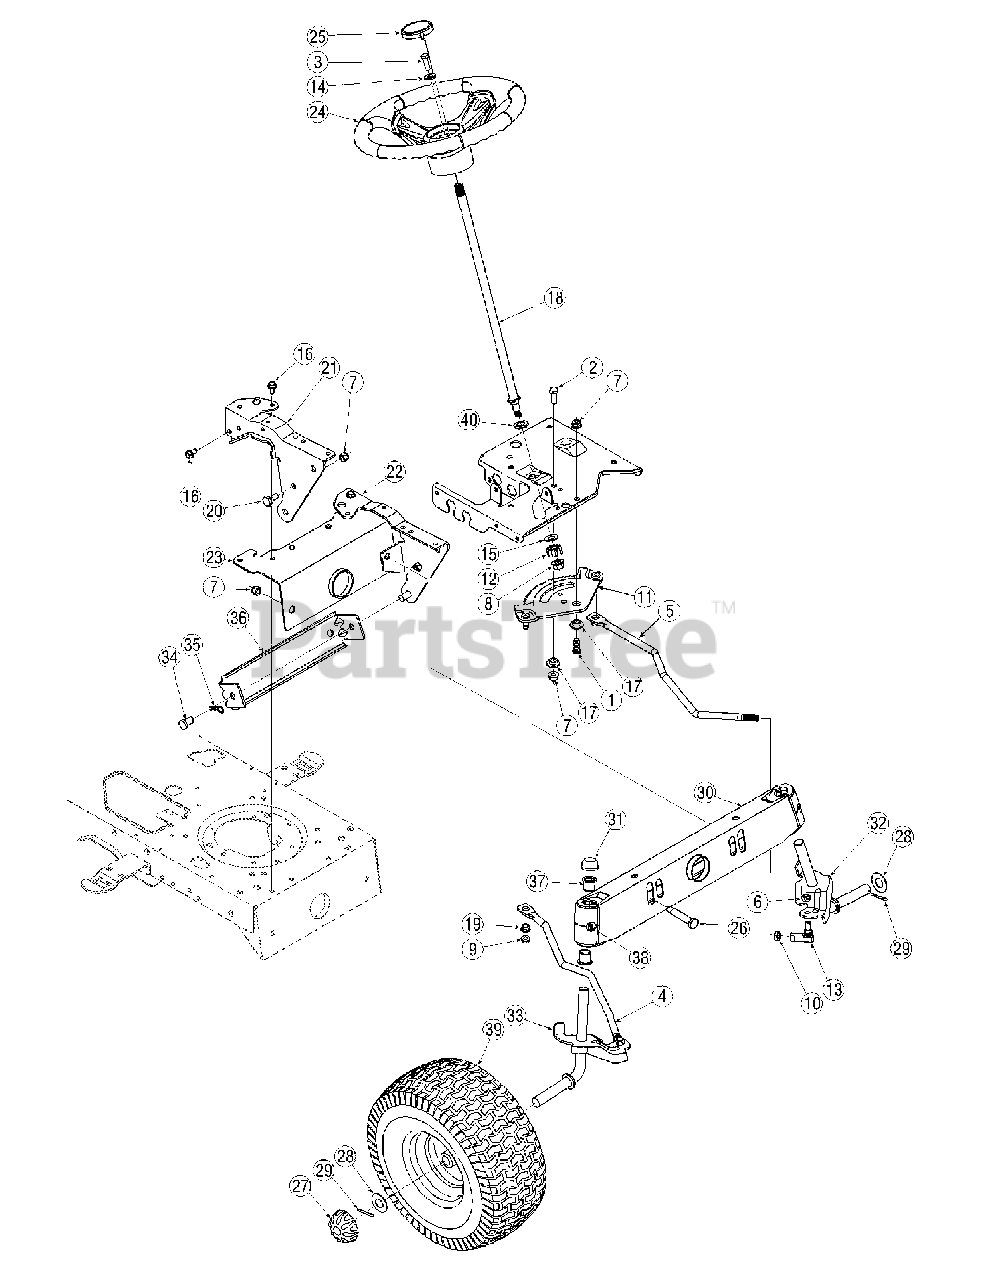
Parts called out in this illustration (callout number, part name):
1	Hex Screw, 3/8-16, 1.00, Gr5
2	Hex Screw, 3/8-16, 1.00, Gr5
3	Hex Screw, 5/16-18, 1.00, Gr5
4	Link, Drag, RH
5	Link, Drag, LH
6	Nut, Hex Lock, 3/8-24
7	Nut, Flange Lock, 3/8-16, Grf, Nylon
8	Nut, Flange Lock, 7/16-20
9	Nut, Flange Lock, 5/16-18, Gr5
10	Nut, Jam, 7/16-20, Gr2
11	Gear, Steering, 11/90 Ratio
12	Gear, Pinion, Steering
13	Ball Joint, 7/16-20, Lock
14	Washer, Flat,.406 x.875 x.105
15	Washer, Flat,.51 x 1.12 x.06
16	Screw, 5/16-12, 0.750
17	Spacer, Shoulder,.38 x 1.00 x.31
18	Shaft, Steering,.625 OD x 24.25 Lg
19	Plastic Bushing.380 ID
20	Screw, Shoulder,.498 x.340, 3/8-16
21	Pivot Bracket, Support RH
22	Pivot Bracket, Support LH
23	Pivot Bracket, Bar
24	Steering Wheel
25	Steering Wheel Cap
26	Shoulder Screw,.5 x 2.2, 3/8-16
27	Deluxe Hub Cap
28	Flat Washer,.78 x 1.589 x.06
29	Cotter Pin, 5/32 x 1.25
30	Pivot Bar
31	Push Cap
32	LH Axle Assembly,.750
33	RH Axle Assembly,.750
34	Pin, Clevis,.50 x.78
35	Cotter Pin, Internal,.080 x 1.5625
36	Adjustment Bracket, Front
37	Flange Bearing,.760 x.941 x 1.0
38	Pivot Bar Endcap
39	Wheel Assembly Complete, 15 x 6
40	Bearing-Hex Flange 5/8 ID PM
